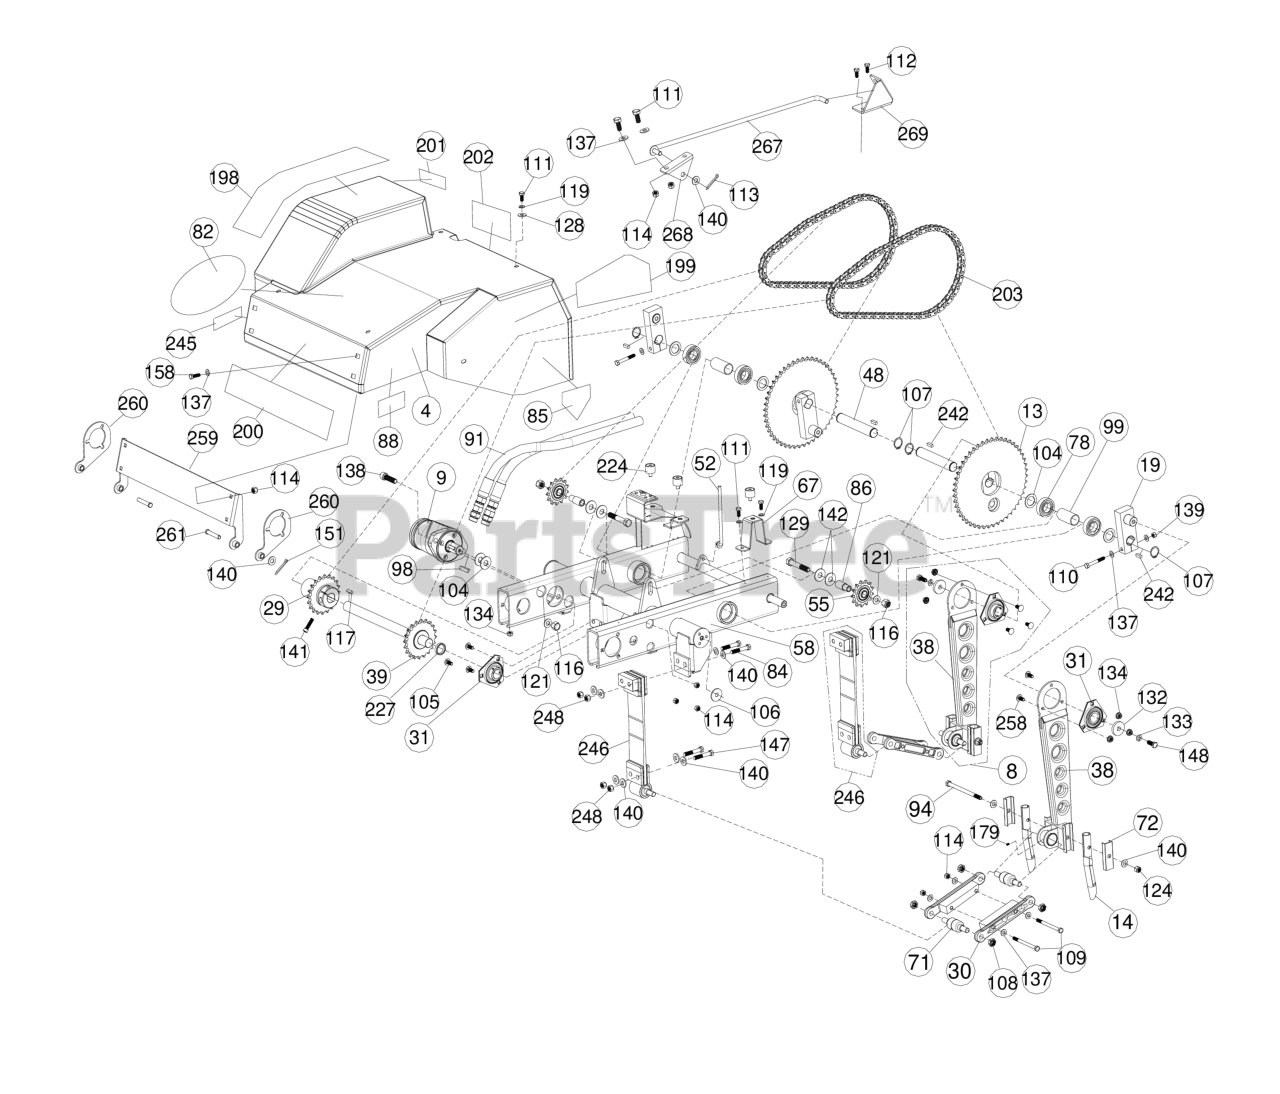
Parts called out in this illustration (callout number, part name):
4	HOOD WA W/LABELS AE1300H
8	TINE ARM ASSY RIGHT AE1300H SERVICE
8	TINE ARM ASSY LEFT AE1300H SERVICE
9	MOTOR TINE DRIVE
13	CRANK DRIVING WA AE900
14	TINE CORING 3/4" X 3"
19	ARM CRANK WA AE900 AE900 PAINTED
29	SPROCKET DRIVE AE900
30	LINK, CAST AE1300H
31	SEE: 362243-S
38	TINE ARM WA
39	SHAFT DRIVE TINE WA AE900
48	SHAFT CRANK AE900
52	ROD PUMP ENGAGE
55	SPROICKET 13T #50 IDLER
58	FRAME TINING AE900
67	BRACKET REAR HOOD
70	BRACKET FRONT HOOD MOUNT
71	BEARING AND SHAFT
72	SEE: 362407-PAINT
78	BEARING 1.00" SEALED PRESS IN
82	LABEL LOGO QB
84	SCREWCAP 3/8"-24 X 2 3/4"GR.8
85	LABEL WARNING OPEI
86	SPACER SPROCKET IDLER 1.3
88	LABEL DANGER
91	HOSE HYDRAULIC W#10 JIC
94	SCREWCAP 3/8"-16 X 5 3/4" GR 8
98	KEY #15 HI PRO
99	SPACER SPINDLE BEARING AE900
104	MACHINE BUSHING 1" X 1 1/2" X 14 GA
105	BOLT CARRIAGE 5/16"-18 X 3/4" ZP
106	WASHER ADHESIVE BACKED ISOLATION
107	RING RETAINING EXTERNAL 1.00"
108	NUT 1/2"-20 JAM W/LOCK
109	SCREWCAP 5/16-18 X 4" ZP GR 5
110	SCREWCAP 5/16-24 X 2 1/4 GR 8 W/PATCH
111	SCREWCAP 5/16"-18X3/4" HCS ZP
112	SCREW SELF TAP 1/4"-20 X 5/8" HWH TYPE F
113	PIN HAIR 1/4" Z/P
114	NUT LOCK 5/16"-18 HEX Z/P
116	NUT LOCK 1/2"-13 HEX
117	KEY SQUARE 1/4" X 1"
119	WASHER LOCK 5/16 ST MED
121	WASHER 1/2" SAE Z/P
124	NUT LOCK 3/8"-16 HEX
128	WASHER 5/16" FLATWASHER Z/P
129	SCREWCAP 1/2-13 X 3" Z/P
132	WASHER 1.5 OD X .453 ID X .25 THK
133	WASHER LOCK 3/8" S/T MED
134	NUT FLANGE 5/16"-18 ZP
137	WASHER 5/16" SAE Z/P
138	SHCS 1/2"-13 X 1.750" ZP
139	NUT 5/16"-24 FIN HEX Z/P
140	WASHER 3/8"SAE 13/32"X13/16"X1/16"
141	SHCS 5/16"-18 X 1.25 BLK OX
142	WASHER 1/2"FC9/16"X1 3/8"X7/64"
147	SCREWCAP 3/8" X 2 1/4" GR 8 ZP
148	SCREWCAP 3/8"-24 X 1" HCS GR 8
151	PIN COTTER 1/8" X 1" Z/P
158	SCREWCAP 5/16"-18 X 1" HCS ZP
198	LABEL BADGING RISER
199	LABEL BADGING SIDE
200	LABEL BADGING FRONT
201	LABEL WARNING HIGH PRESSURE
202	LABEL INSTRUCTION HYDRAULIC
203	CHAIN #50 X 70 PITCHES O-RING
224	VIBRATION MOUNT
227	SPACER 1.25 OD X 1.010 ID .258 LONG
242	KEY 1/4" SQ X 0.75"
243	NUT LOCK 3/8"-24 HEX ZP
245	LABEL HOT SURFACE
246	SPRING ARM ASSY AE900H SERVICE
248	NUT LOCK 3/8"-24 HEX ZP
258	BOLT, CARRIAGE 5/16-18 X 1" ZP SHORT NK
259	HOOD BRACKET FRONT AED
260	HOOD HINGE AEH
261	.375 CLEVIS PIN
267	HOOD LIFT ROD
268	HOOD GUIDE BRACKET UPPER
269	HOOD GUIDE BRACKET LOWER
